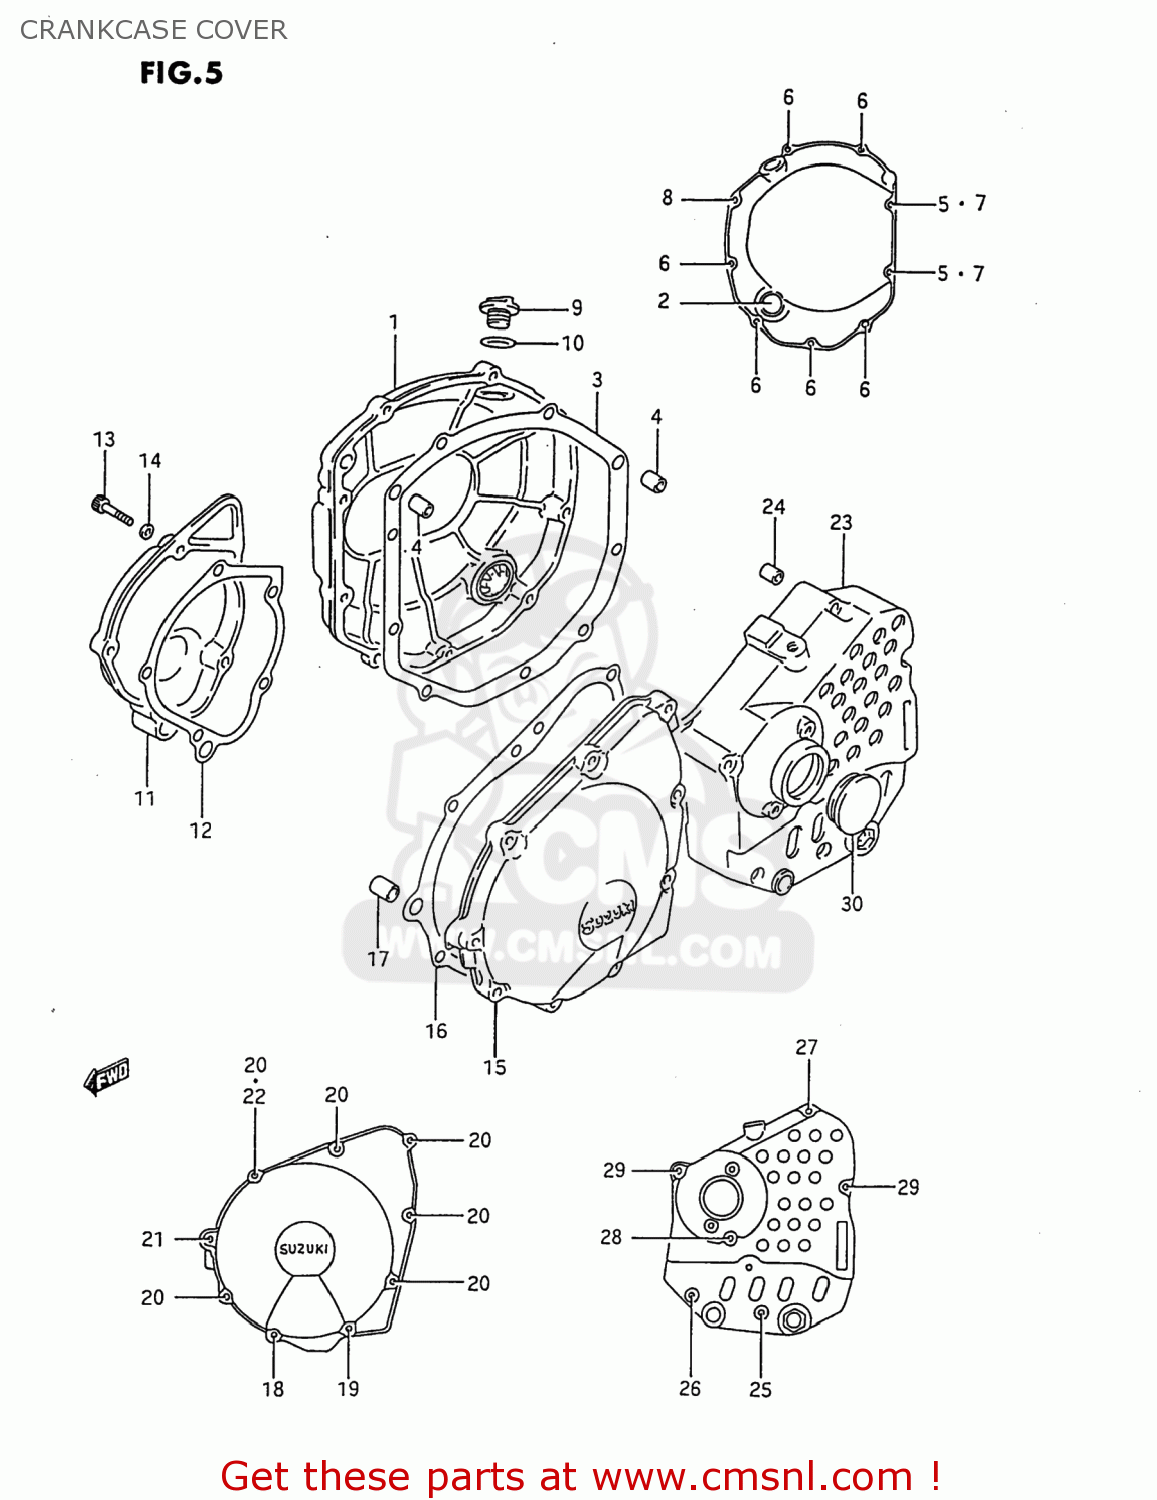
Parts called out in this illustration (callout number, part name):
1	COVER COMP,CLUTCH
2	LENS,OIL LEVEL CHECK
3	GASKET,CL COVER (NAS)
4	PIN
5	GASKET(5.8X11X1.2) (NAS)
6	BOLT,CL.COVER
7	BOLT
8	BOLT
9	PLUG
10	O RING(D:3.1,ID:16.8)
11	COVER,SIGNAL GENERATOR
12	GASKET,SIGNAL GEN COVER (NAS)
13	BOLT(6X22)
14	GASKET(5.8X11X1.2) (NAS)
15	COVER,STARTER GEAR
16	GASKET,STARTER GEAR COVER (NAS)
17	PIN(8.4X11X20)
18	BOLT,OIL FILLE
19	BOLT,CRKCASE,R
20	BOLT,CL.COVER
21	BOLT
22	GASKET(5.8X11X1.2) (NAS)
23	COVER,ENGINE SPROCKET
24	PIN
25	BOLT
26	BOLT
27	BOLT
28	BOLT
29	BOLT
30	CAP(OD:36)
